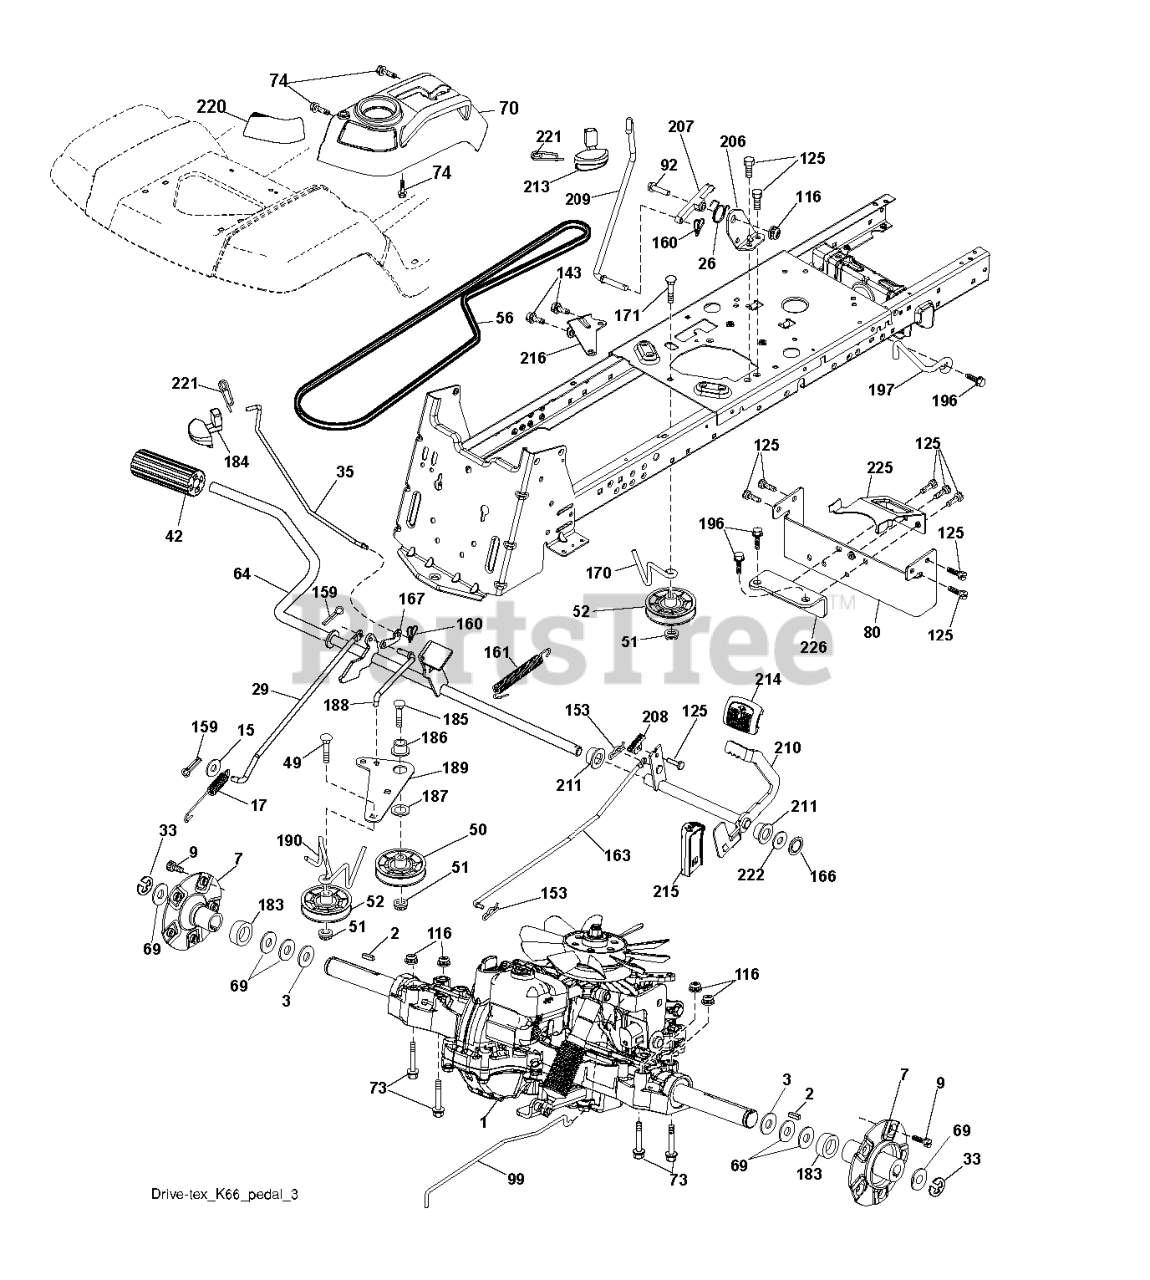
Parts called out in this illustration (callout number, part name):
2	KEY 1/4 X 2.5
7	HUB.ASM.WHEEL.REAR.23"TEX
15	WASHER
17	SPRING.BRAKE.K46
26	SPRING.RETURN.CRUISE
29	ROD.BRAKE.K66
33	E RING HYT
35	ROD.BRAKE.PARKING.GT.H
42	PEDAL COVER T
50	IDLER.FLAT.910.OFFSET
51	NUT LOCK FLG 3/8-16 UNC
52	IDLER.V-GROOVE.910.OFFSET
64	SHAFT.ASM.PEDAL.BRK.CNTR
70	RP CONSOLE.ASM.PCH.W/TB
73	BOLT HEX 5/16-18 GR 5
74	SCREW.HI-LO.CONSOLE
80	STRAP.TORQUE.K66
92	BOLT
99	ROD.SPRING.BYPASS.K66.GT.Z
116	NUT LOCK HEX FLANGE 5/16-18
125	SCREW
143	Screw 5/16-18 x 1/2 Hex, Self Tapping 5/16-18 x 1/2
153	RETAINER M
159	COTTER PIN
160	RETAINER CLIP
161	SPRING, RETURN LT
163	ROD.PEDAL.CONTROL
166	NUT.PUSH.625
167	LATCH.BRAKE.SPRING
170	KEEPER.V-IDLER.CENTER.
183	SPACER.AXLE.HG.TEX
184	HANDLE.PARKG.BRK.HUSQ X667
186	SPACER.RETAINER
187	WASHER 12/32X2X10GA
188	RP.LINK.CLUTCH.GROUND.DRIVE
189	BELLCRANK.GROUND.DRIVE.TEX.
190	KEEPER.BELLCRANK.DRIVE
196	SCREW 3/8-16X1
197	BRKT.ANIT-ROTATION.CLUTCH
206	BRKT.MOUNT.LATCH.CRUIS
207	LATCH.CONTROL.CRUISE
208	GEAR.SECTOR.CONTROL.CR
209	ROD.CONTROL.CRUISE.GT.
210	ROCKER.ASM.PEDAL.CONTR
211	BEARING.NYLON
213	KNOB.CONTROL.CRUSIE.HU
214	PEDAL.FORWARD.PAD.TEX
215	PEDAL.REVERSE.TEX.GT.4
216	BRACKET.PULLEY.IDLER.W/TEX
220	REFLECTOR.RH.TEX GT
221	RETAINER.SPRING.CLIP.H
222	WASHER 21/32 X 1-1/4 X 10 GA.
225	KEEPER.BELT.TRANSAXLE.K66
226	BRACKET.MOUNT.TORQUE.K66.TG
